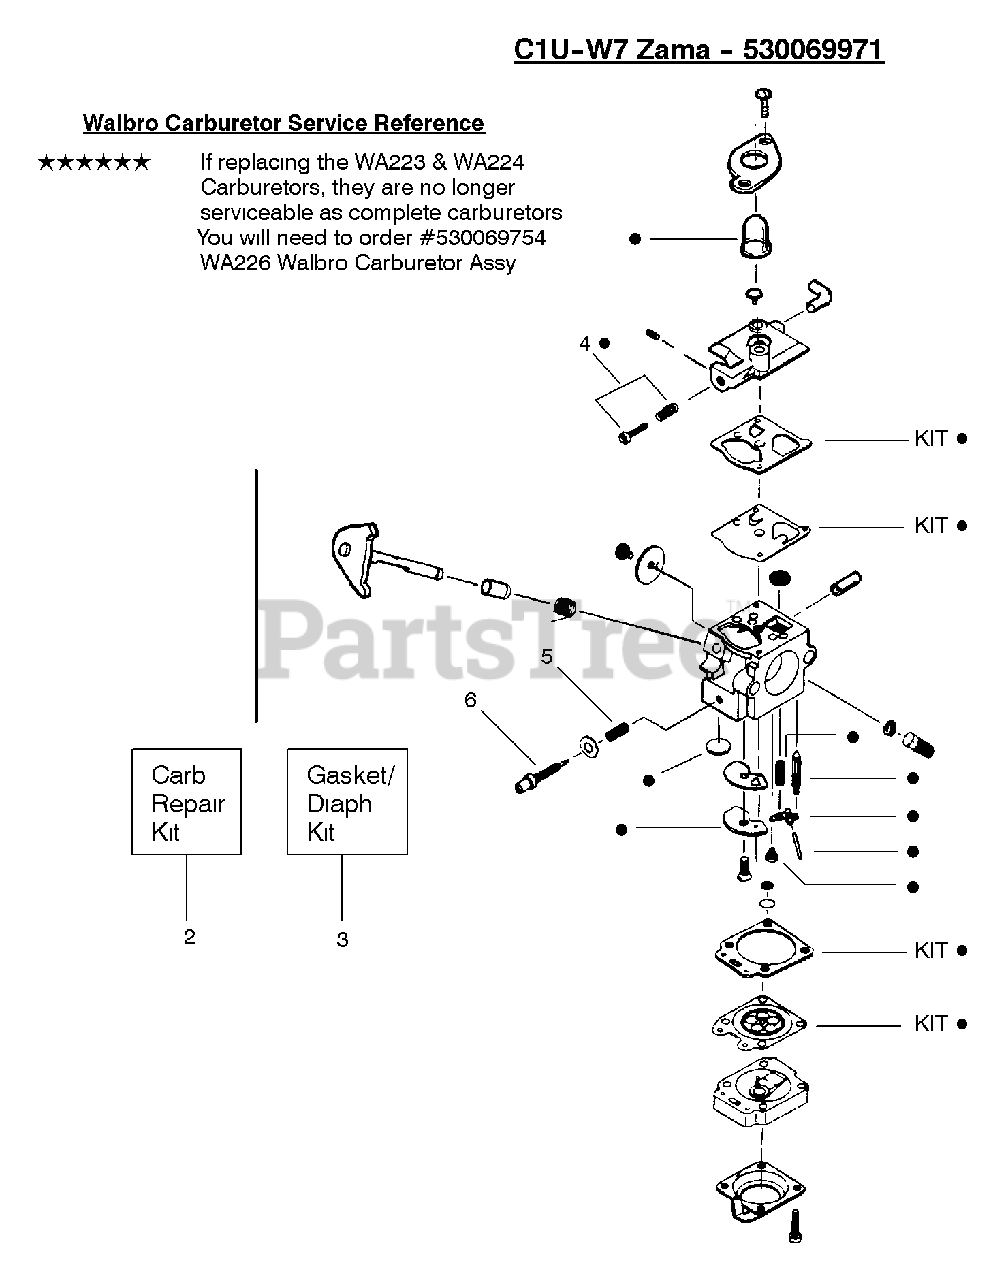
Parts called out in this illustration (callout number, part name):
2	Carburetor Repair Kit C1UW7
3	Gasket/Diaphragm C1UW7 (Zama)
4	Idle Screw & Spring Kit
5	Low Speed Spring
6	Low Speed Needle
530069971	Carburetor Assembly (Zama C1U-W7)
